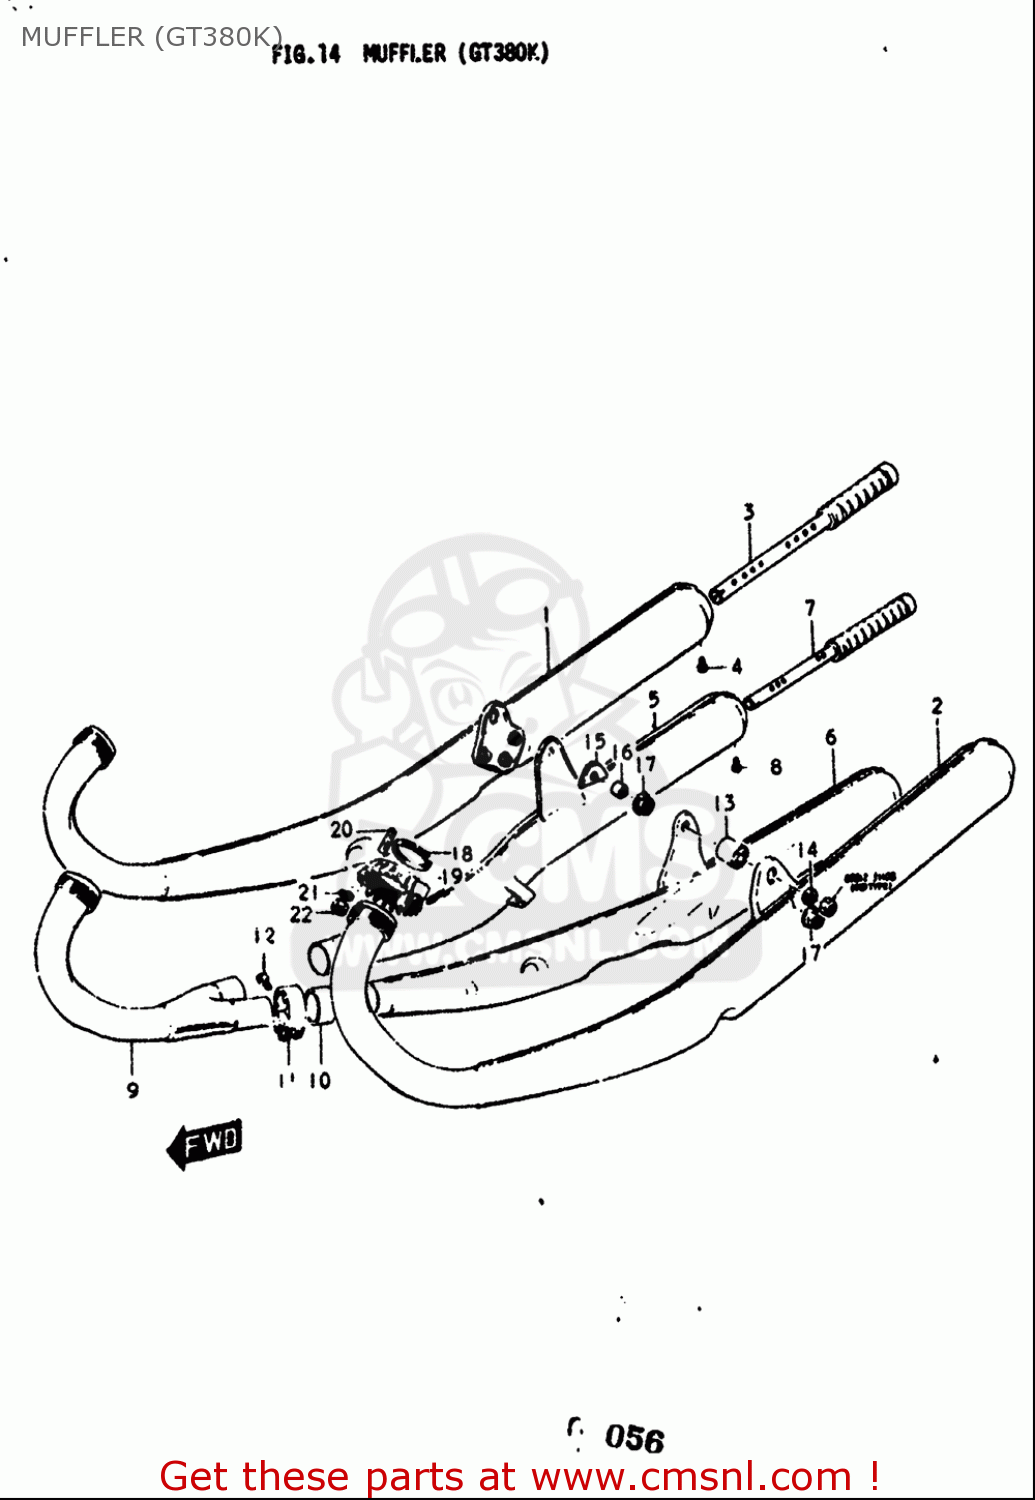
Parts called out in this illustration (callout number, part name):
3	PIPE,BAFFLE
4	SCREW(5X6)
7	PIPE,BAFFLE
8	SCREW(5X6)
10	CONNECTOR,MUFFLER
11	CLAMP
12	SCREW
13	BUSHING(10X23X35)
14	WASHER
15	DAMPER,MUFFLER SUPPORT BRACKET
16	SPACER(10.1X15X4.8)
17	NUT (M10X1.25X9)
18	GASKET,EXHAUST PIPE (NAS)
20	STUD
21	WASHER,LOCK
22	NUT
